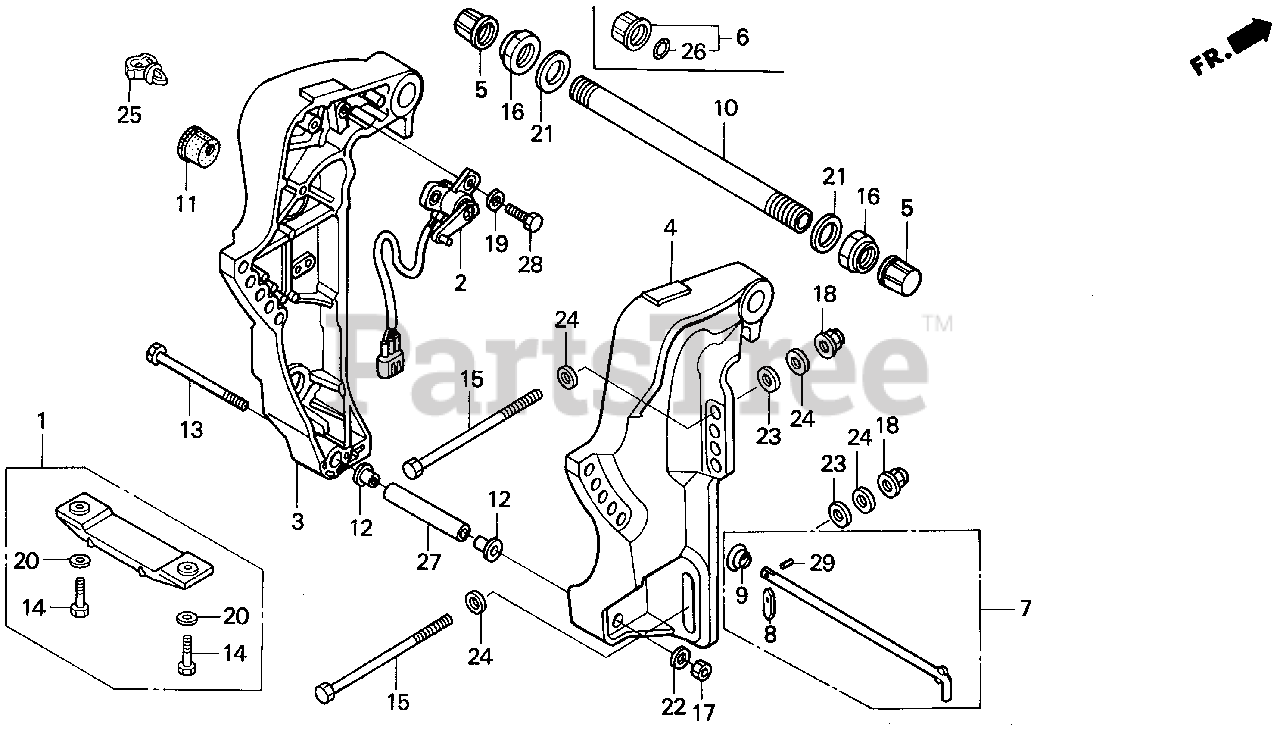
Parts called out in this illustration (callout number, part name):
1	METAL KIT, ANODE
2	SENSOR ASSY., TRIM ANGLE
3	BRACKET, L. STERN *NH282MU* (OYSTER SILVER METALLIC-U)
4	BRACKET, R. STERN *NH282MU* (OYSTER SILVER METALLIC-U)
5	CAP, TILTING BOLT
7	ROD, ADJUSTING
8	STOPPER, ROD
9	SPRING, ADJUSTING ROD
10	SHAFT, TILTING
11	BUSH, MOTOR CODE
12	BUSH, CYLINDER (LOWER)
13	BOLT, HEX. (10X158)
14	BOLT, HEX. (6X25)
15	BOLT, HEX. (12X100)
16	NUT, SELF-LOCK (7/8-14UNF)
17	NUT, SELF-LOCK (10MM)
18	NUT, SELF-LOCK (12MM)
19	WASHER, PLAIN (6MM)
20	WASHER, PLAIN (6MM)
21	WASHER, WAVE (22MM)
22	WASHER, PLAIN (10MM)
23	WASHER, PLAIN (12MM)
24	WASHER, PLAIN (12MM)
25	CLIP, WIRE HARNESS
26	O-RING (15.54X2.26)
27	COLLAR, DISTANCE (10X90)
28	BOLT, HEX. (6X20)
29	PIN, SPRING (2.5X8)
